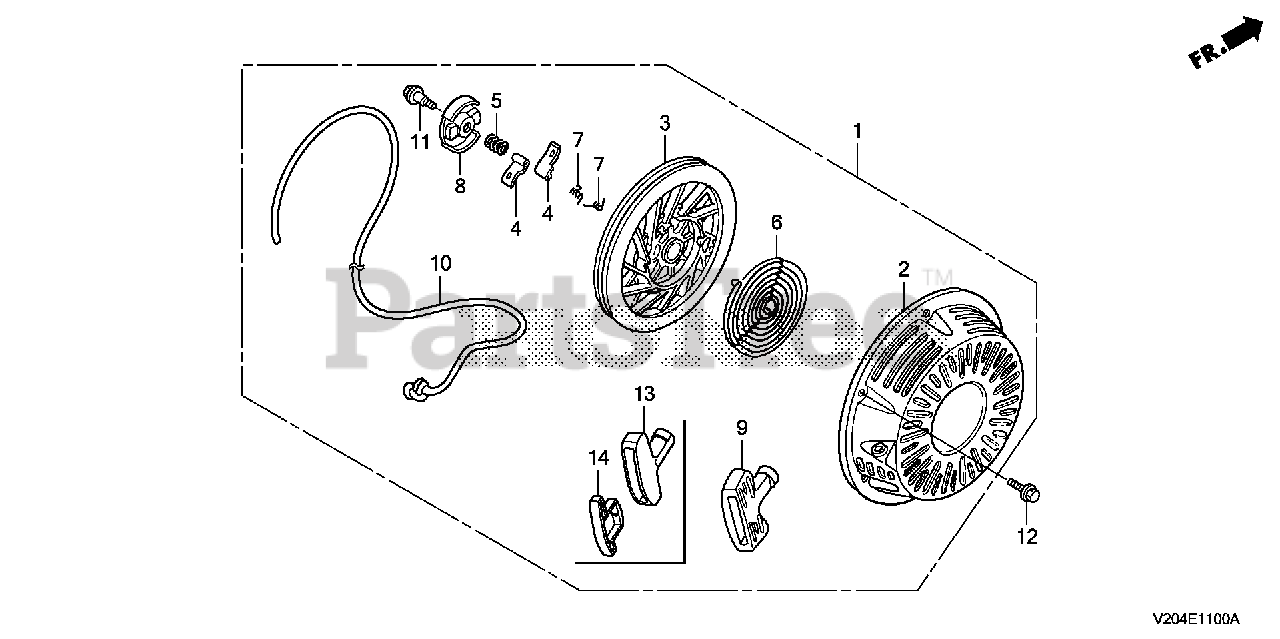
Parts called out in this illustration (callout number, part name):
1	STARTER ASSY., RECOIL *R280* (COO)(FOR U.S.A.) (POWER RED)
2	CASE, RECOIL STARTER *R280* (POWER RED)
3	PULLEY, RECOIL STARTER
4	RATCHET, STARTER
5	SPRING, FRICTION
6	SPRING, STARTER RETURN
7	SPRING, RATCHET
8	RETAINER, SPRING
10	ROPE, RECOIL STARTER
11	SCREW, CENTER
12	BOLT, FLANGE (6X10)
13	GRIP, STARTER (COO)(FOR U.S.A.)
14	GRIP, REINFORCEMENT
